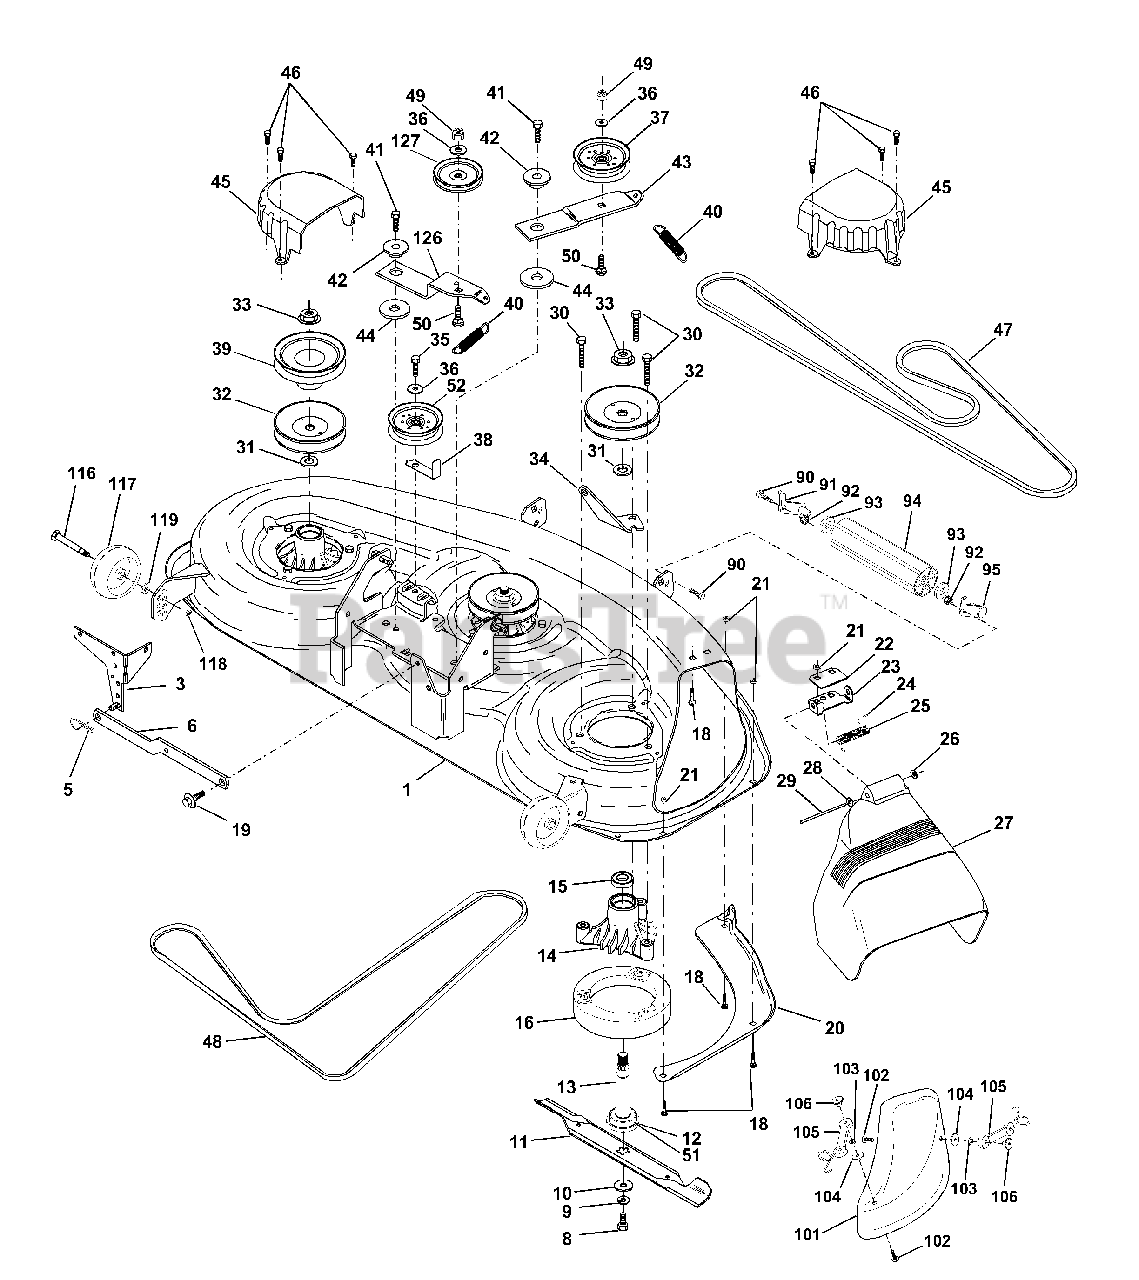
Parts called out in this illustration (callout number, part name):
1	Deck Asm., Mower 46"
3	Bracket Asm., Sway Bar
5	Retainer Spring
6	Arm, Suspension, Rear (Sway Bar)
8	Bolt, Patched 3/8-24 x 1-1/4 Gr. 8
9	Washer, Lock Hvy., Unplated 3/8
10	Washer, Hard Blade, Mower Vented
11	Blade, 46" Mower Deck
12	Bearing, Ball, Mandrel #6204
13	Shaft Asm. w/Lower Bearing
14	Housing, Mandrel
15	Bearing, Ball, Mandrel
16	Stripper, Mower Round
18	Bolt, Carriage 5/16-18 x 5/8
19	Bolt, Hex Head, Shoulder 5/16-18
20	Baffle, Vortex Mower 46"
21	Nut, Crownlock 5/16-18 UNC
22	Stiffener, Bracket
23	Bracket, Deflector
24	Cap, Sleeve
25	Spring, Torsion, Deflector
27	Shield, Deflector Mower
28	Washer 11/32 x 5/8 x 16 Ga.
29	Rod, Hinge
30	Screw, Hex Head, Thdroll
31	Washer, Spacer Mower Vented
32	Pulley, Mandrel
33	Nut, Flg. Top Lock Cntr. 9/16
34	Anchor, Spring Deck 46"
35	Screw, Thdroll 3/8-16 x 1-3/4 Tytt
36	Washer 13/32 x 13/16 x 16 Ga.
37	Pulley, Idler, Flat
38	Keeper, Belt, Idler
39	Pulley, Idler, Driven
40	Spring, Secondary 44/46/50 Vent
41	Screw, Thdroll 3/8-16 x 1-1/4 Tytt
42	Spacer, Retainer
43	Arm, Idler Secondary
44	Washer, Hardened
45	Cover, Mandrel Deck
46	Screw, Thdroll. 1/4-20 x 5/8
47	V-Belt, Mower, Secondary
48	V-Belt, Mower, Primary
49	Nut, Crownlock 3/8-16 UNC
50	Bolt, Carriage 3/8-16 x 1-1/2 Gr. 5
51	Washer Felt
90	Bolt, Fin, Hex 3/8-16 UNC x 1
91	Bracket, Asm Noseroller, LH
92	Nut, Lock, Hex w/Ins 3/8-16UNC
93	Washer 17/32 x 7/8 x 16 Ga.
94	Roller, Nose 38 & 42
95	Bracket, asm Noseroller RH
101	Cover, Mulching
102	Screw
103	Washer, Lock #10
105	Latch Asm. Bagger
106	Nut, Weld
116	Bolt, Shoulder
117	Gauge Wheel
118	Nut, Centerlock 3/8-16 UNC
119	Washer 3/8 x 7/8 x 14 Ga.
126	Arm, Idler, Primary Deck 46"
127	Pulley, Idler, V-Groove Dim. 4.25
